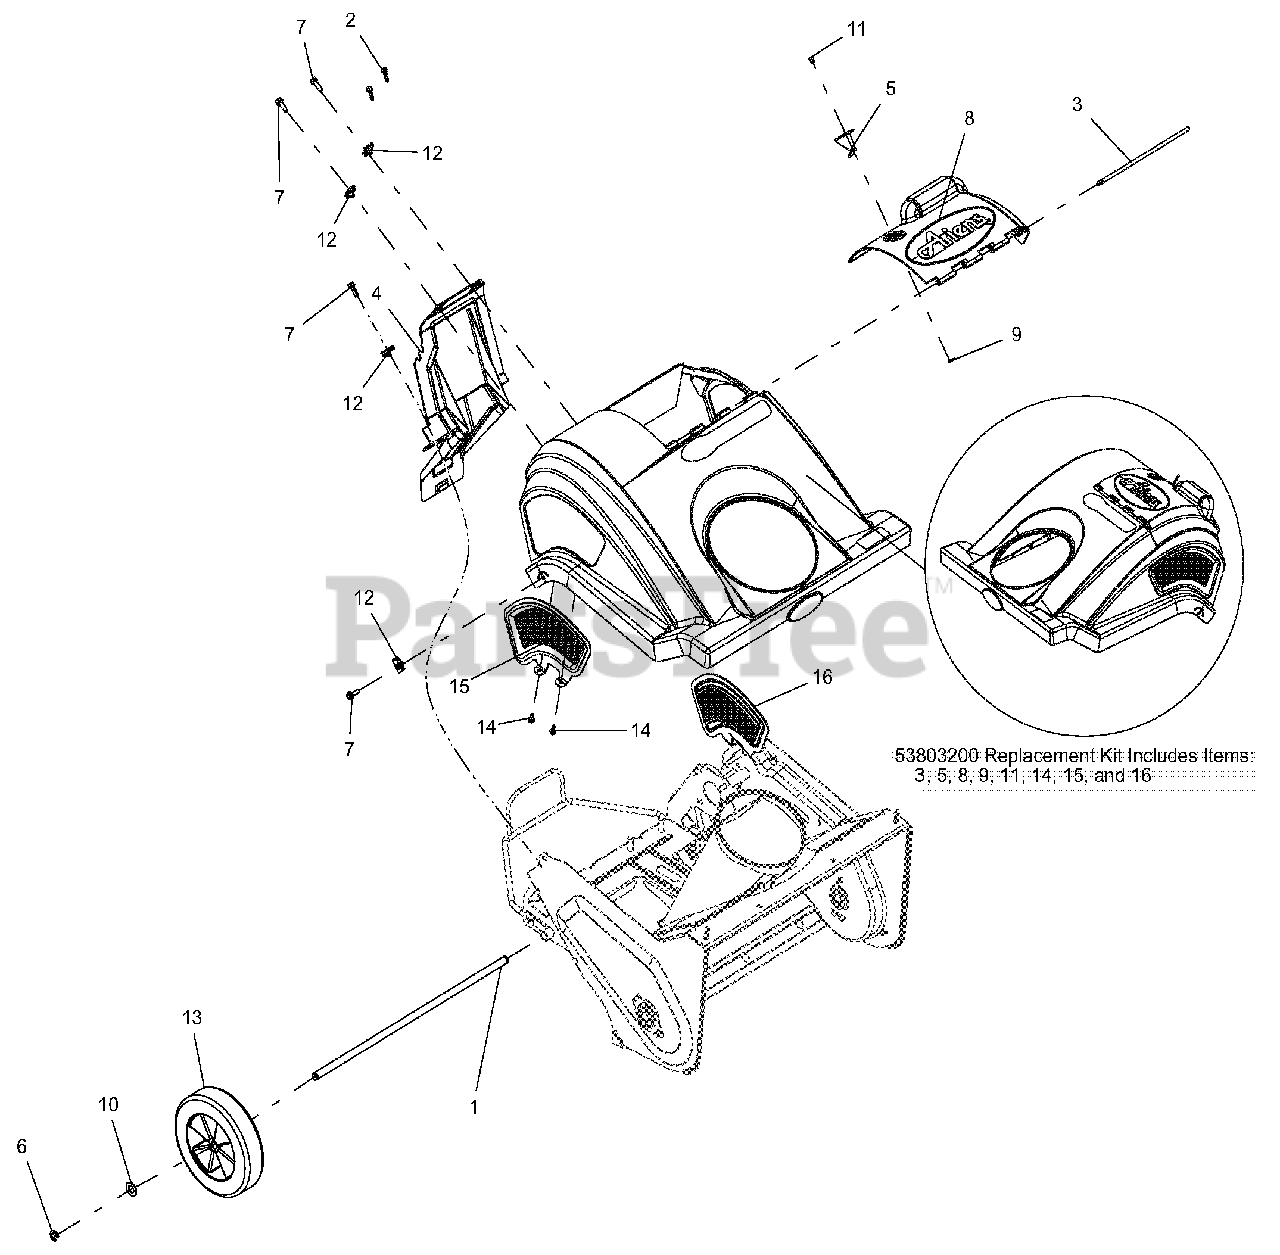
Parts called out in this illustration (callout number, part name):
1	SHAFT, AXLE
2	SCR-TAP #12X.75 BOSS INDHXHD
3	ROD, COVER, SINGLE STAGE
4	COVER, BACK ELECTRIC START
5	TAB, LATCH
6	RG-RTNG-EXT .500X.042 (E)
7	BLT-HEX .25-20X.75 HWH YZ GR5
8	DOOR, COWEL COVER
9	WSHR-FL-STL .196X.500X.06 YZ
10	WSHR-FL-STL.531X1.00X.063 YWZC
11	RVT-POP .187 YZ
12	NUT-RTNR .25-20X.56
13	WHL 7.50" .50 BORE, 1.50 HUB
14	SCR-TAP #10X.50 BOSS INDHXHD
15	RIGHT VENT, COVER
16	VENT, COVER LEFT
